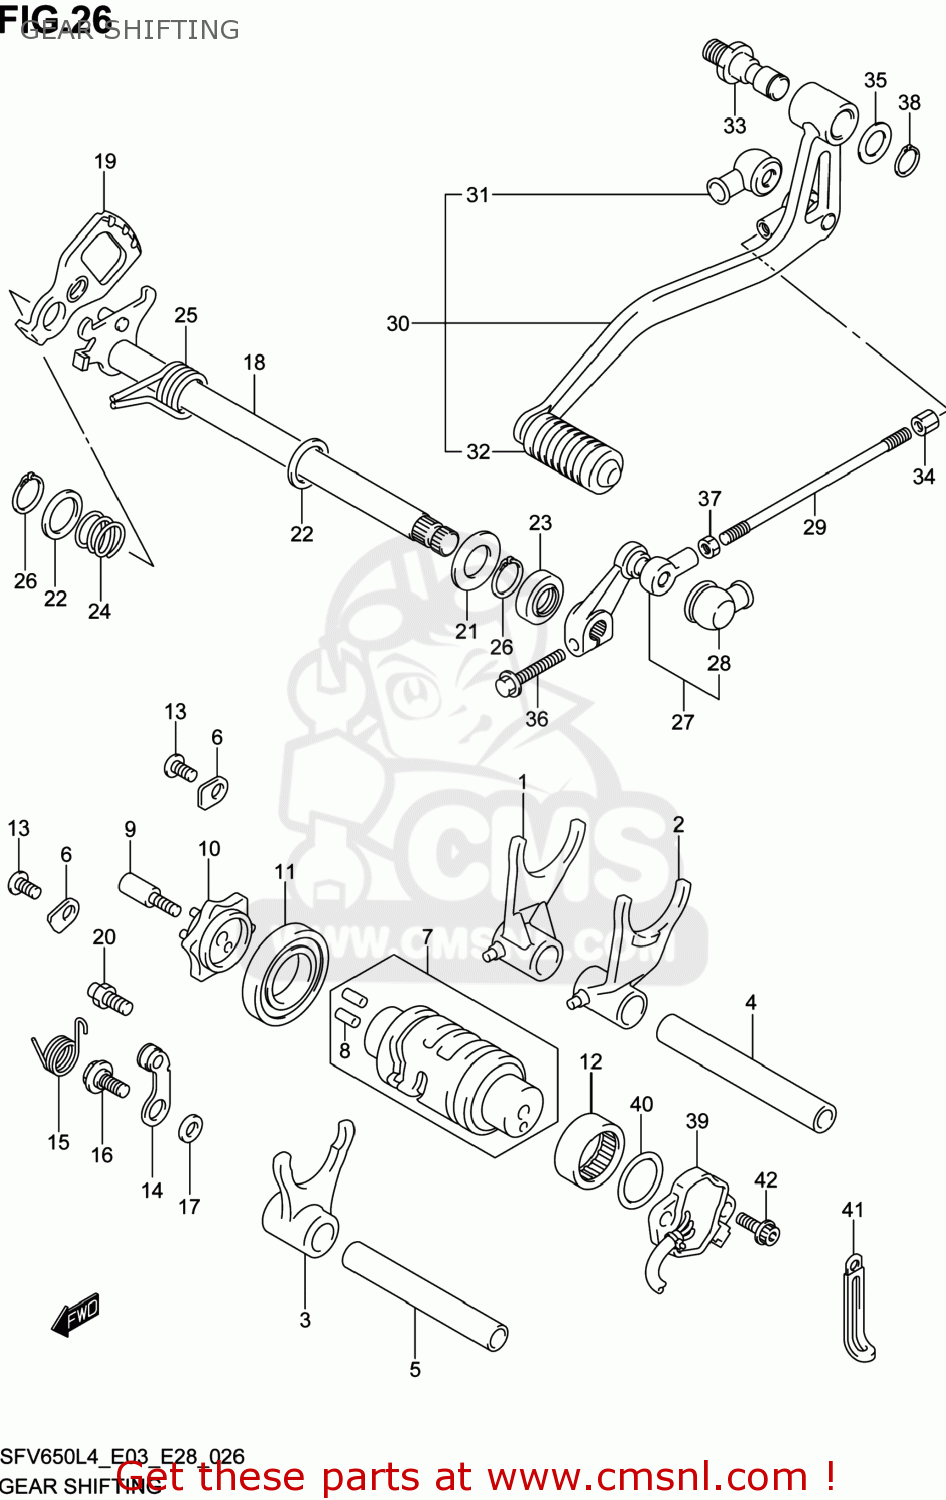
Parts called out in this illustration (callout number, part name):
1	FORK,GEAR SHIFT NO.1
2	FORK,GEAR SHIFT NO.2
3	FORK,GEAR SHIFT NO.3
4	SHAFT,GEAR SHIFT FORK
5	SHAFT,GEAR SHIFT FORK NO.1
6	RETAINER
7	CAM,GEAR SHIFT
8	PIN
9	BOLT,GEAR SHIFT CAM PLATE
10	PLATE,GEAR SHIFT CAM
11	BEARING(25X47X8)
12	BEARING(25X32X12)
13	SCREW
14	STOPPER,SHIFT CAM
15	SPRING,SHIFT
16	BOLT(6X14.3)
17	WASHER
18	SHAFT,GEAR SHIFT
19	PLATE,GEAR SHIFT CAM DRIVE
20	STOPPER,GEAR SHIFT ARM
21	WASHER(14X29X0.8)
22	SHIM(14X22X1)
23	SEAL,OIL(14X22X7.3)
24	SPRING
25	SPRING
26	CIRCLIP
27	ARM,GEAR SHIFT LINK
28	COVER,DUST
29	ROD,GEAR SHIFT LINK
30	LEVER ASSY,GEAR SHIFT
31	COVER,DUST
32	RUBBER,GEAR SHIFT PEDAL
33	SHAFT,GEAR SHIFT LEVER
34	NUT
35	WASHER(12.5X20X1)
36	BOLT
37	NUT
38	CIRCLIP
39	SENSOR ASSY,GEAR POSITION
40	O RING(D:2.4,ID:26.2)
41	CLAMP(L:80)
42	BOLT(5X16)
